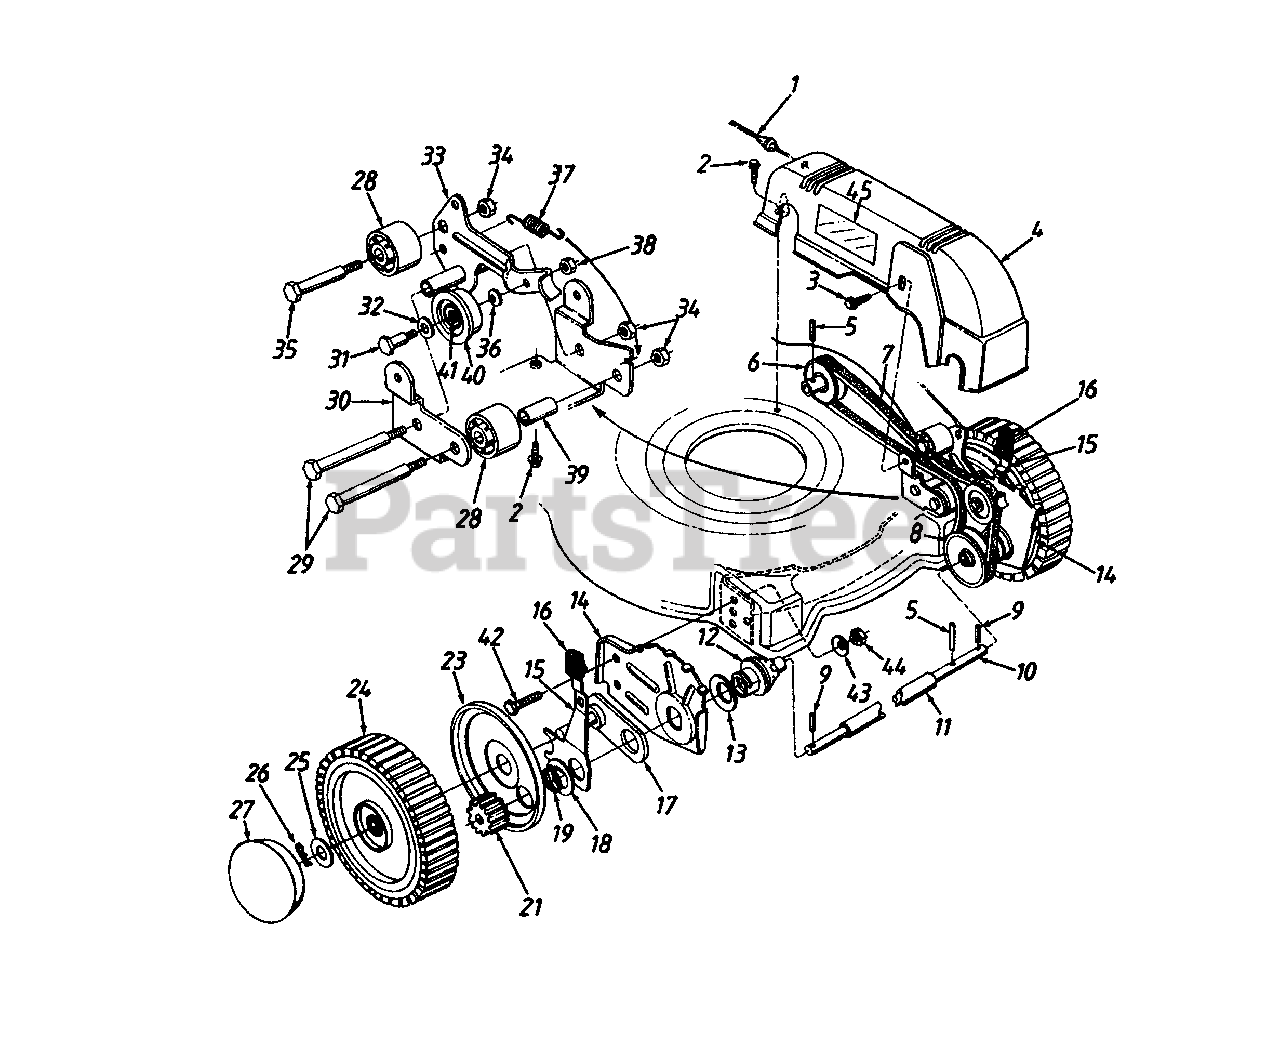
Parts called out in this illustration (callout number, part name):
1	S.R Cable 44.75" Lg.
2	Hex Wash. Hd. TT-Tap Scr. 1/4-20 x .5" Lg.
3	Hex Wash. Hd. Tap Scr. 1/4-20 x .38" Lg.
4	Belt Cover
5	Spring Pin 3/16" Dia. x 1.25" Lg.
6	3/8" 'V'-Pulley 2.75" O.D.
7	'V'-Belt
8	3/8" 'V'-Pulley 2.44" O.D.
9	Spring Pin 3/16" Dia. x .875" Lg.
10	Front Axle
11	Axle Shroud
12	Front Bearing Ass'y.
13	Wave-Wash. 1.01" I.D.
14	Height Adj. Plate-R.H.
15	Spring Lever-R.H.
16	Spring Lever Knob
17	Height Adj. Pivot Plate Ass'y.
18	DD Washer 1.5" O.D.
19	Snap Ring
21	14-T Spur Gear
23	Wheel Dust Cap
24	Front Wheel Ass'y.
25	Fl-Wash. .531" I.D. x 1" O.D.
26	Hairpin Clip
27	Hub Cap-3-1/2" Dia.
28	Idler Ass'y.
29	Shld. Bolt .374" Dia. x 1.94"
32	Fl-Wash. .39" I.D. x 1" O.D.
35	Shld. Bolt 3/8" Dia. x 1.16"
36	Bell-Wash. .265" I.D. x .75" O.D.
37	Spring Extension 1.29" Lg.
38	Hex Nut 1/4-28 Thd.
39	Spacer .385" I.D. x .625" O.D.
40	Fl-Idler 1.5" O.D.
41	Needle Brg. .375" I.D.
42	Hex Bolt 3/8-16 x .62" Lg.
43	Bell-Wash. .39" I.D. x 1.13" O.D.
44	Hex Nut 3/8-16 Thd.
45	Foil Label
